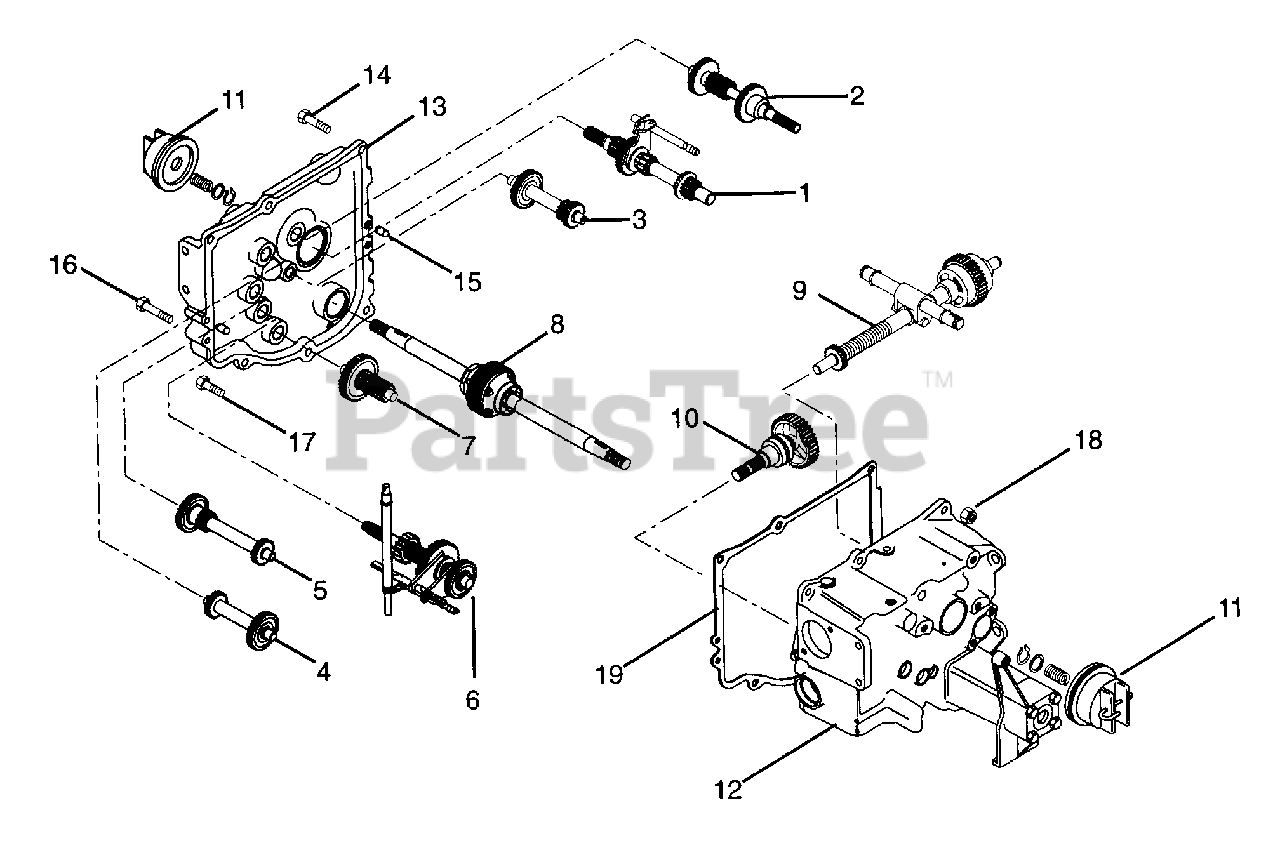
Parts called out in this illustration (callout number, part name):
14	Bolt-Hex .38-16 x 2.00 Grade 5
15	Pin-Dowel .38 x .625
16	Bolt-Hex .38-16 x 2.25 Grade 5
17	Bolt-Hex .38-16 x 1.50 Grade 5
18	Nut-Locking-Center .375-16 Grade 2
19	Gasket-Transmission Cover
